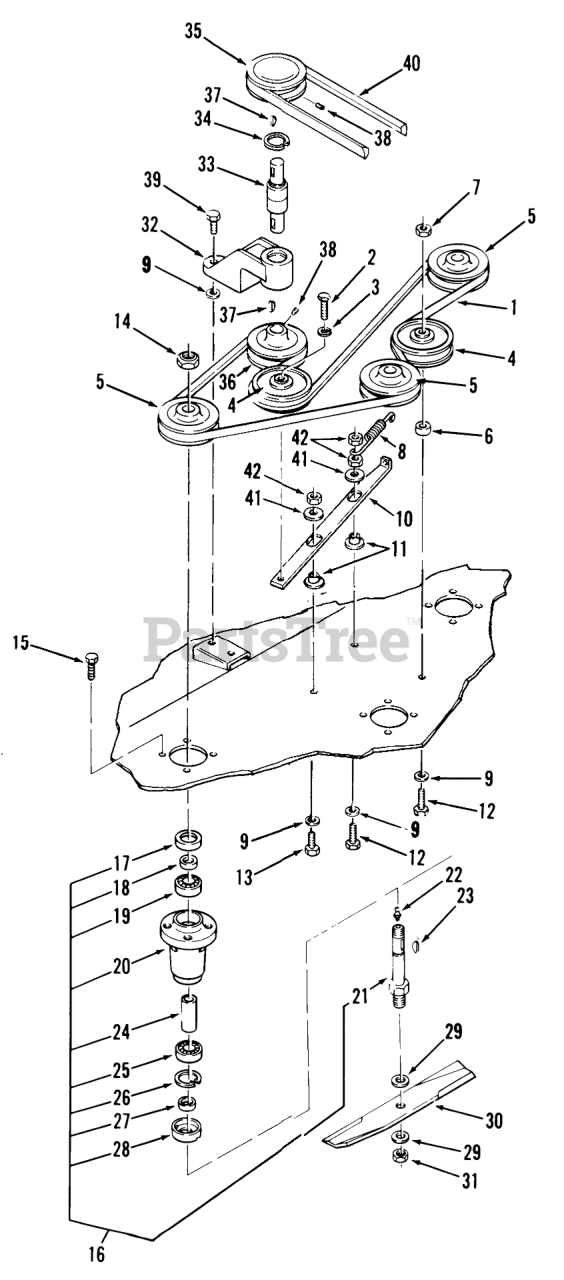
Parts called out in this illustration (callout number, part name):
1	V-BELT
2	BOLT HEX SPECIAL
3	LOCKWASHER
4	Idler Pulley
5	PULLEY-BLADE DRIVE
6	SPACER
7	Nut
8	SPRING-EXTENSION
9	WASHER
10	BAR-SLIDER
11	SPACER-BUSHING
12	Bolt
13	Bolt
14	Nut
15	Bolt
16	Spindle Assembly
18	SPACER-SEAL
19	BEARING-BALL
20	HOUSING-SPINDLE
21	Spindle Shaft
22	Grease Fitting
23	Hi-Pro Key 3/16 x 5/8
24	SPACER
25	BEARING-BALL
26	Ring-Snap
27	SPACER-BLADE
28	CUP-SPINDLE
29	SpeciaI Washer
30	BLADE KIT
31	Nut
32	HOUSING DRIVE BRG R
33	BEARING-INT SHAFT
34	Snap Ring
35	PULLEY
36	Pulley
37	KEY-WOODRUFF
38	Set Screw
39	Bolt
40	Drive Belt
41	WASHER
42	NUT
